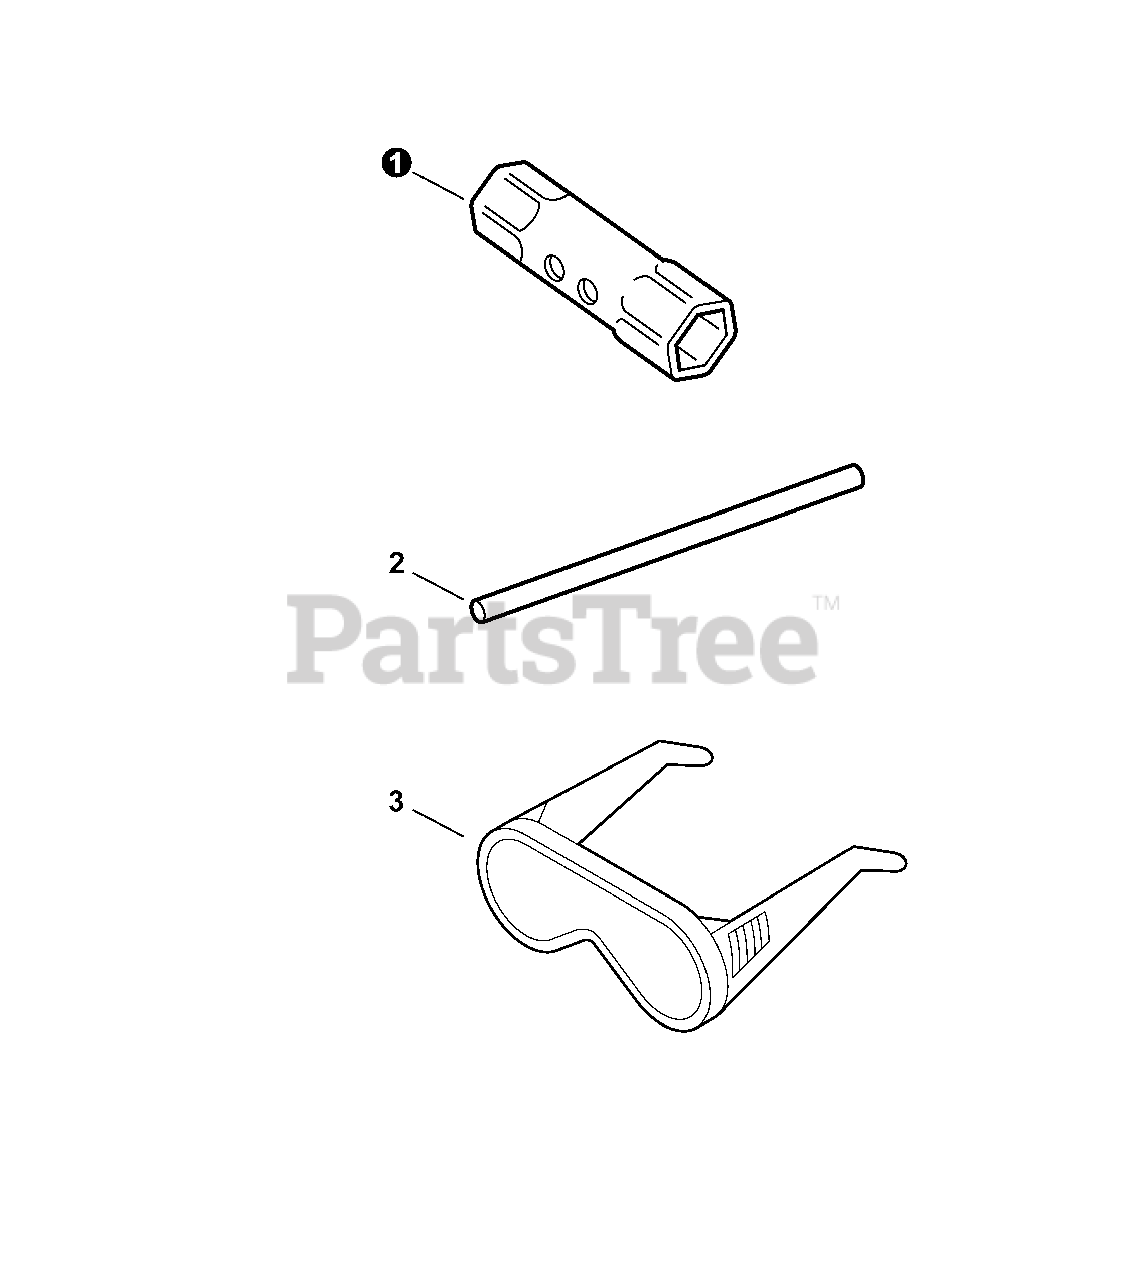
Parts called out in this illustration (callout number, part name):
1	SOCKET WRENCH
2	ROD, LOCKING - 5×120mm
3	GOGGLES
